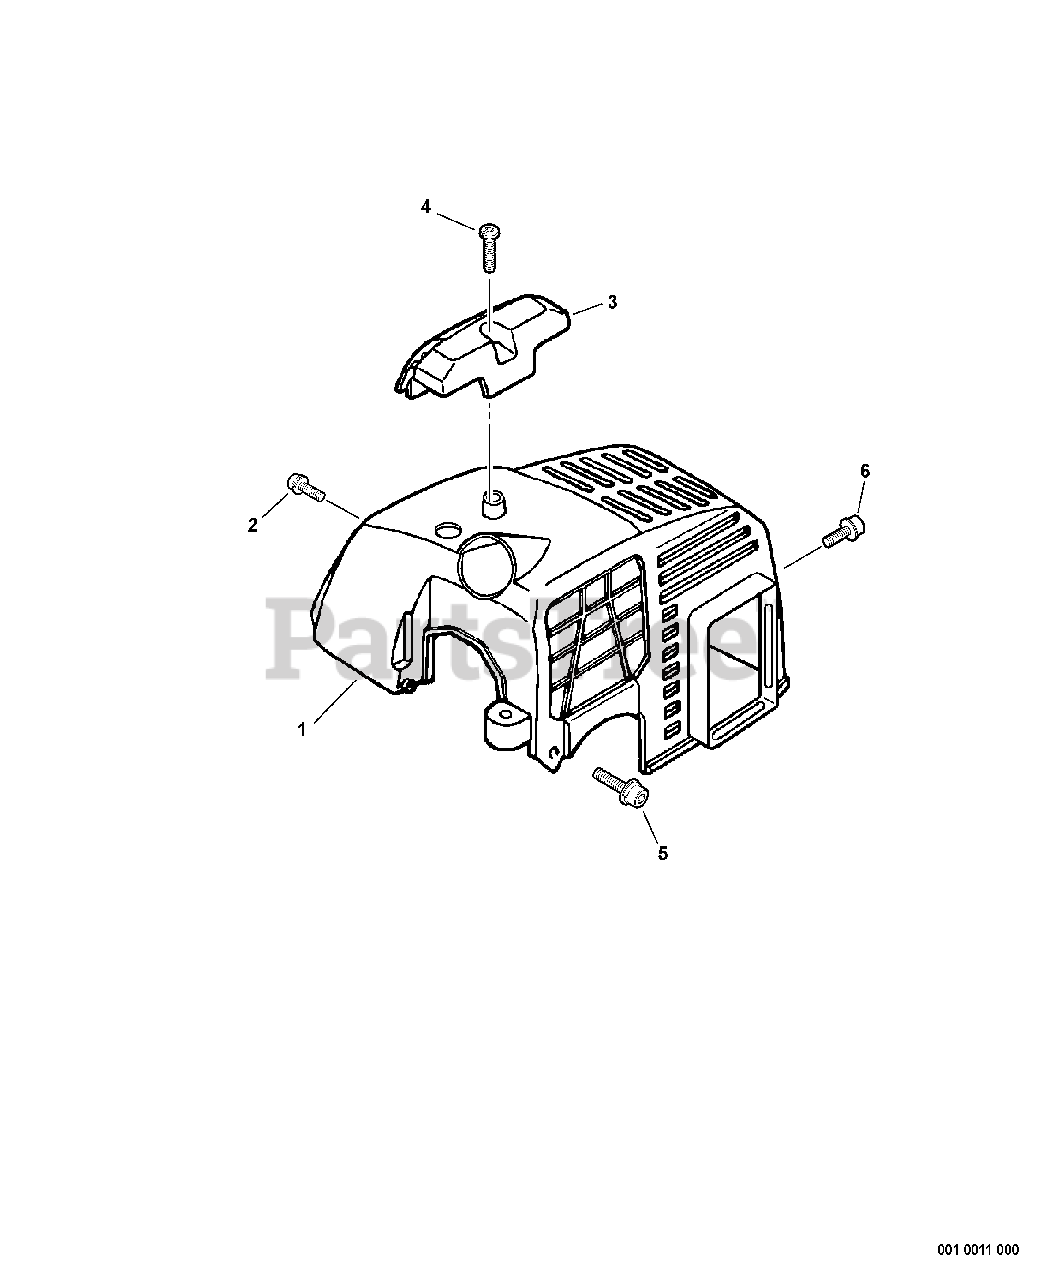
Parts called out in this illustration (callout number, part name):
1	COVER, ENGINE
2	SCREW 4×12
3	GUARD, TOP
4	SCREW 5×16
5	BOLT 4×16
6	BOLT 4×8
